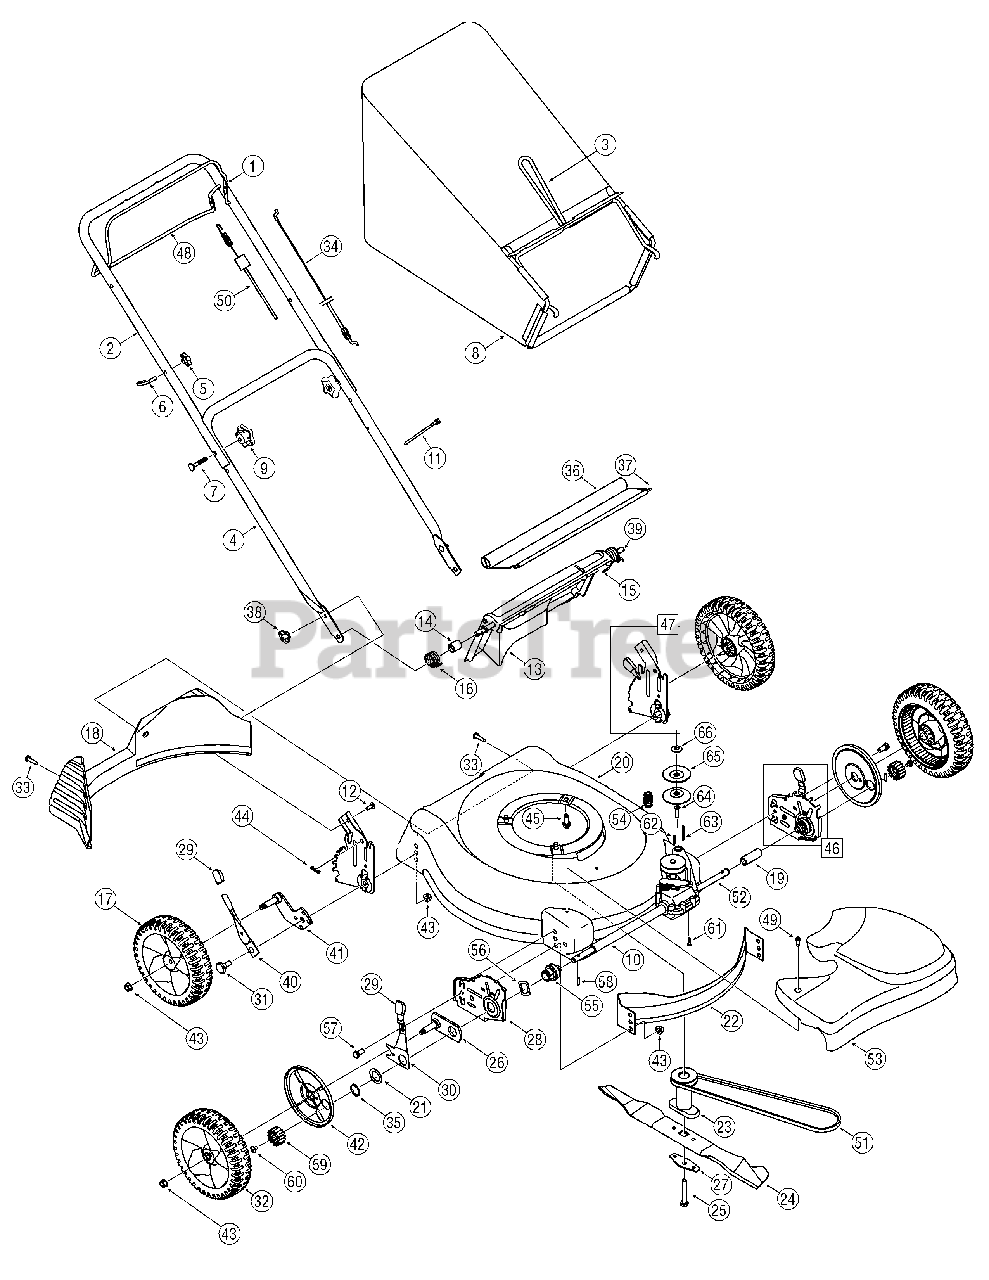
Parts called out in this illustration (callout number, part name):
5	Wing Nut
6	Rope Guide
7	Carriage Bolt, 5/16-18 x 2
8	Grass Bag Assembly
9	Hand Knob
10	Sleeve Spacer - RH
11	Cable Tie
12	Carriage Bolt ,1/4-20
13	Rear Discharge Door
14	Spacer
15	Torsion Spring - LH
16	Torsion Spring - RH
17	Rear Wheel
18	Rear Baffle
19	Sleeve Spacer - LH
21	Washer, 1.5" OD
22	Front Baffle
23	Blade Adapter w/Pulley
24	21" Mulching Blade
25	Hex Bolt , 3/8-24 x 2.5
26	Pivot Plate Assembly
27	Blade Bell Support
28	Height Adjustment Plate - RH
28	Height Adjustment Plate - LH
29	Adjustment Lever Knob
30	Front Lever - RH
30	Front Lever - LH
31	Shoulder Screw
32	Front Wheel
33	Screw, 1/4-15 x 1.250
34	Control Cable - 40.75"
35	Snap Ring
36	Trailshield
37	Trailshield Wire
38	Wing Nut, 1/4-20
39	Rear Door Pivot Rod
40	Spring Lever
41	Pivot Arm Assembly - RH
41	Pivot Arm Assembly - LH
42	Wheel Dust Cap
43	Flange Lock Nut, 3/8-16
44	Hairpin Clip
45	TT Sems Screw, 3/8-16 x 1.00
46	Ht. Adj. Assy. Front - LH
46	Ht. Adj. Assy. Front - RH
47	Rear Handle Bracket Assy. LH
47	Rear Handle Bracket Assy. RH
48	Drive Control
49	Shoulder Screw
50	Drive Cable
51	V-Belt
52	Transmission Assembly
53	Front Drive Cover
54	Belt Tension Spring
55	Bearing Assembly
56	Wave Washer
57	Hex Screw
58	Dowel Pin
59	Gear, 14T - RH
59	Gear, 14T - LH
60	Screw, 1/4-20 x .390
61	Torx Screw
62	Spirol Pin
63	Dowel pin
64	Screw, #12-16 x 1.00
65	Pulley, 3.82 x .313 x .68
66	Bell Washer, .325 x .930 x .45
